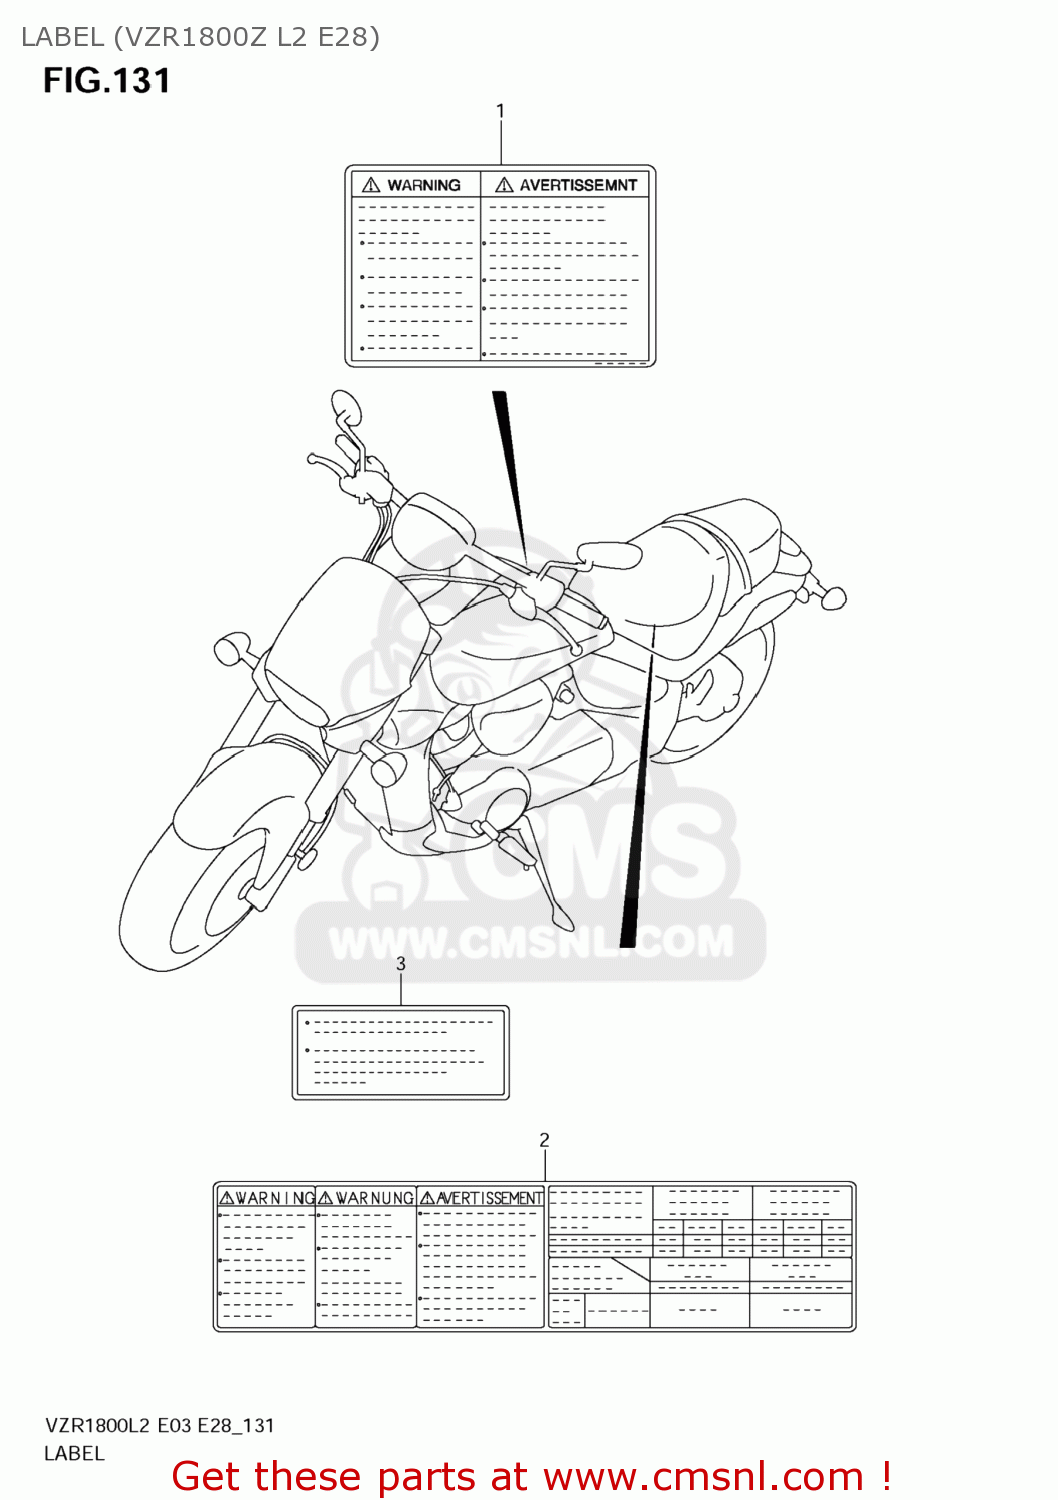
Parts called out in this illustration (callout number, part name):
1	LABEL,GENERAL WARNING
2	LABEL,TIRE INFORMATION
3	LABEL,FUEL INFORMATION
4	MANUAL,OWNER'S
